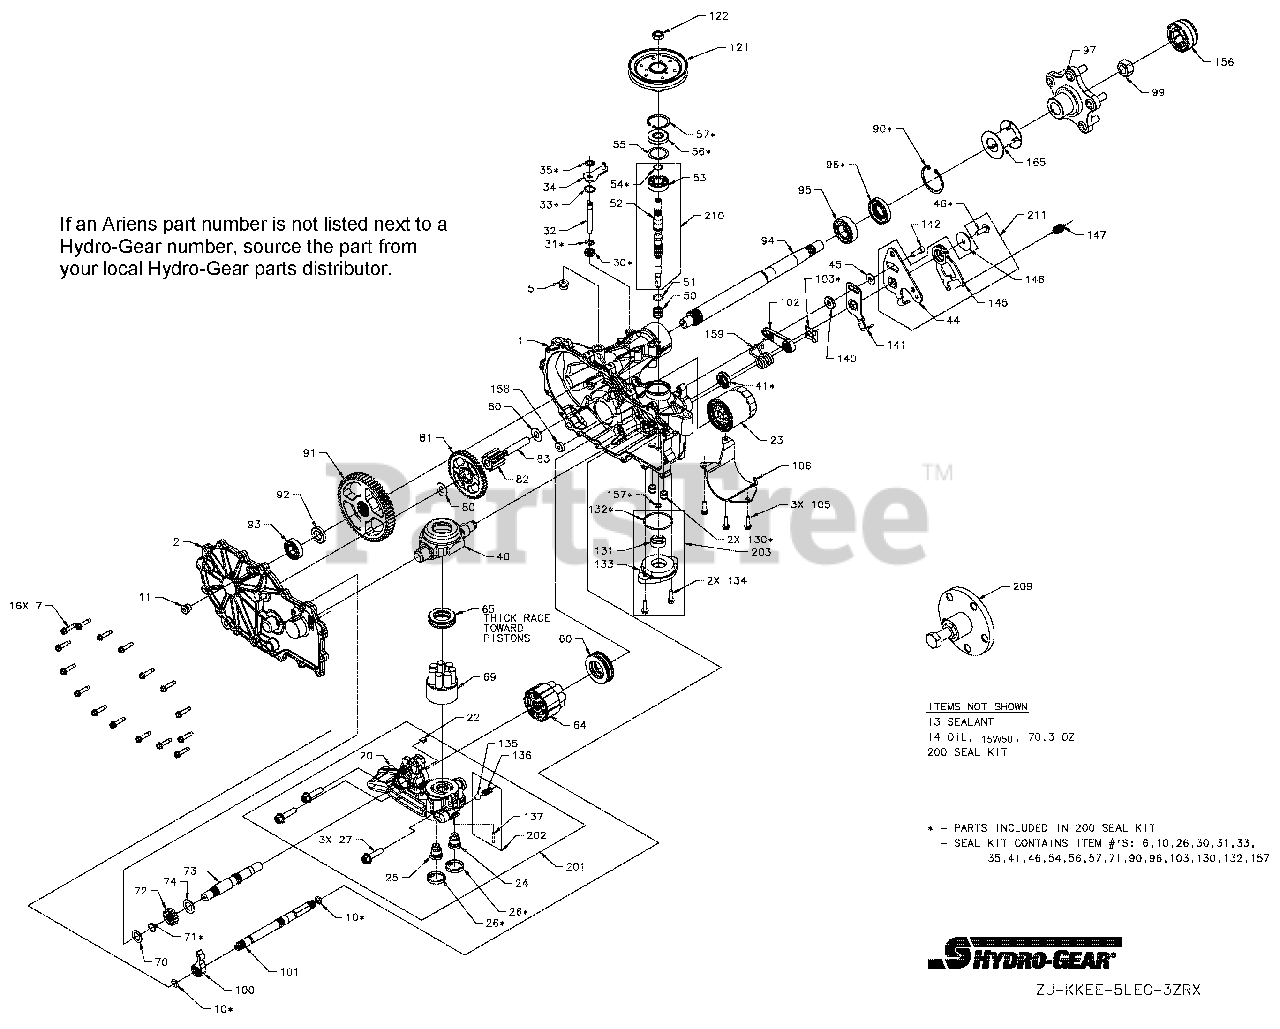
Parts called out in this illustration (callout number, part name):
1	KIT, HOUSING,MAIN,LH,CHRG,CNTL
1	HOUSING, MAIN, LH, CHRG, CNTL
1	BUSHING, .624 x .719 x .562
1	BRG, JRNL .86 x .98 x .79
1	PIN, .25 x .375
2	KIT, COVER, SIDE, LH
2	COVER, SIDE, LH
2	BUSHING, .624 x .719 x .562
2	BRG, JRNL .86 x .98 x .79
5	PLUG 9/16-18 (METAL)
7	HFHCS 1/4-20 x 1.125"
10	O-RING - 111 .103 x 424
11	PLUG 9/16-18 (METAL)
13	SEALANT
14	SYNTHETIC OIL, 15W50
20	CENTER SECTION, LH, CHRG
22	PLATE, BYPASS
23	FILTER, OIL
24	SHOCK VALVE ASSEMBLY 220 BAR
25	SHOCK VALVE ASSEMBLY 220 BAR
26	SEAL, PLUG 1.250 x .250
27	HFHCS 3/8-16 x 1.5 (PATCH)
27	BEARING, JOURNAL .50 x .59 x .50
30	SEAL, LIP .375 x .75 x .25
31	RING, RET .375 EXTRNL
32	ROD, BYPASS
33	RING, RET .750 INTRNL
34	ARM, BYPASS
35	RING, RTNG .375 EXT
40	TRUNNION, SWASHPLATE
41	SEAL, LIP 12 x 32 x 7
44	ARM, CONTROL, LH
45	WASHER .34 x .88 x .06
46	TWHCS 5/16-24 x 1.00 (PATCH)
50	SPRING, BLOCK
51	WASHER-FLAT .59 x .79 x .04
52	SHAFT, INPUT
53	BRG, BALL 17 x 40 x 12
54	RING, RET. WIRE .561
54	RING, RET WIRE .561 ID
55	WASHER 1.23 x 1.56 x .04
56	SEAL, LIP 17 x 40 x 7
57	RING, RETAINING
60	BEARING, THRUST
64	ASS'Y, CYLINDER BLOCK, 16cc
65	BRG, THRUST PLASTIC CAGE
69	ASS'Y, BLOCK 7 PISTON
70	WASHER .63 x 1.0 x .05
71	RING, RETAINING_.625
72	GEAR, 13T, STEEL
73	SHAFT, MOTOR
74	WASHER .72 x 1.16 x .04
80	WASHER .5 x 1.0 x .03
81	GEAR, 46T
82	GEAR, 11T, STEEL
83	JACK SHAFT (PIN)
90	RING, RET 2.06 INT
91	GEAR, 54T
92	SPACER, .750 x 1.320 x .257
93	BEARING, BALL, .75 x 40 x 12
94	SHAFT, AXLE
95	BRG, BALL 25.4 x 52 x 15
96	SEAL, LIP 1.000 x 2.049 x .375
97	KIT, HUB, 5 BOLT
97	HUB, TAPER 3.56, 5 BOLT
97	STUD, 1/2-20 x 1.5 (RIB NECK)
99	NUT, HEX LOCK 3/4-16
100	PAWL, BRAKE
101	SHAFT, BRAKE
102	KIT HANDLE, ACTUATING
103	CLIP, RETAINING
105	SCREW, HEX FLANGE 1/4-20 x .625
106	GUARD, FILTER, LH
121	PULLEY, 4.5 x 1.625
122	NUT,HEX JAM 1/2-20 W/ PATCH
130	TUBE, CONNECTING
131	GEROTOR ASSEMBLY (1.9 cc/rev)
132	O-RING, -137, 0.103 x 2.050
133	COVER, CHARGE PUMP
134	SCREW, HEX FLANGE 1/4-20 x .625
135	BALL 7/16
136	SPRING, RELIEF
137	PIN, SPRING .125 x .875
140	SPACER .320 x 1.005 x .179
141	ARM, NEUTRAL LEFT
142	SHCS 5/16-24 x 1 PATCH
145	ASSEMBLY, RTN, CCW
146	WASHER, .343 x 1.500 x .062
147	SPRING, EXTNSN RTN-34LBS
157	SEAL, LIP 8 x 12 x 3 VC
158	MAGNET, RING
159	SPRING, TORSION CW
165	TUBE, AXLE 2.04
200	KIT, SEAL
200	PIN, .25 x .375
201	KIT, CENTER SECTION, LH, CHRG
202	KIT, CHARGE RELIEF
203	KIT, CHARGE PUMP
209	HUB PULLER, 5 BOLT
210	KIT, INPUT SHAFT
211	KIT, RTN, CCW
